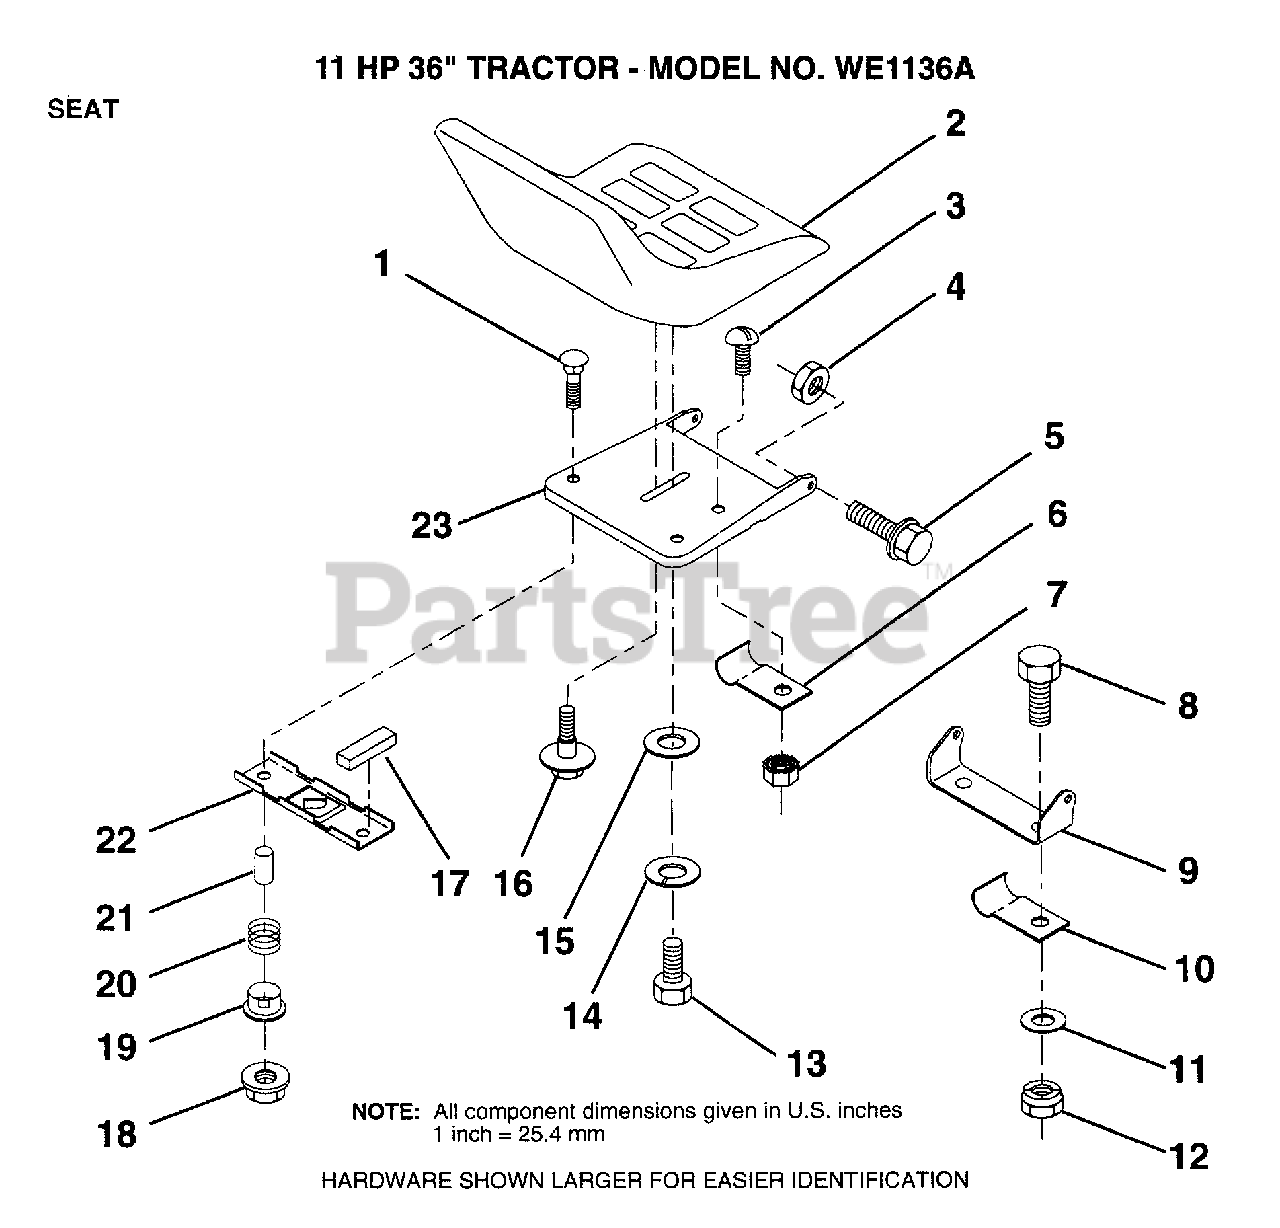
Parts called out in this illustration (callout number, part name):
7	"NUT,KEPS"
10	"CLIP,INSULATOR"
11	WASHER
13	BOLT
14	LOCKWASHER
15	WASHER
16	"BOLT,SHOULDER"
17	STRIP FORM
19	BUSHING
20	SPRING
21	SPLIT SPACER
22	BRKT SWITCH
